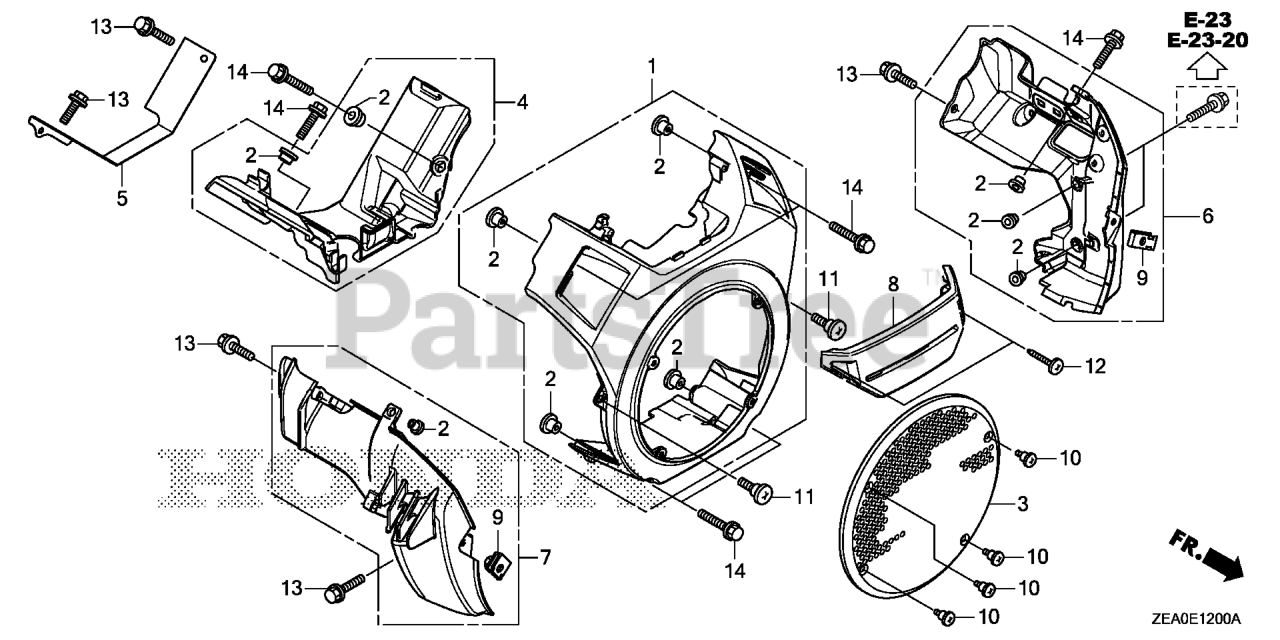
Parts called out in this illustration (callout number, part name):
1	COVER, FAN *R280* (POWER RED)
2	COLLAR, FAN COVER
3	PROTECTOR, FAN COVER
4	SHROUD (UPPER)
5	SHROUD B (UPPER)
6	SHROUD, R. (LOWER)
7	SHROUD, L. (LOWER)
8	COVER, FR. (NOT AVAILABLE)
9	NUT, FENDER SETTING
10	SCREW, SPECIAL (4X10)
11	SCREW, SPECIAL (6X15)
12	SCREW, TAPPING (5X20)
13	BOLT, FLANGE (6X16) Use from Engine SN 2056820.
14	BOLT, FLANGE (6X20)
